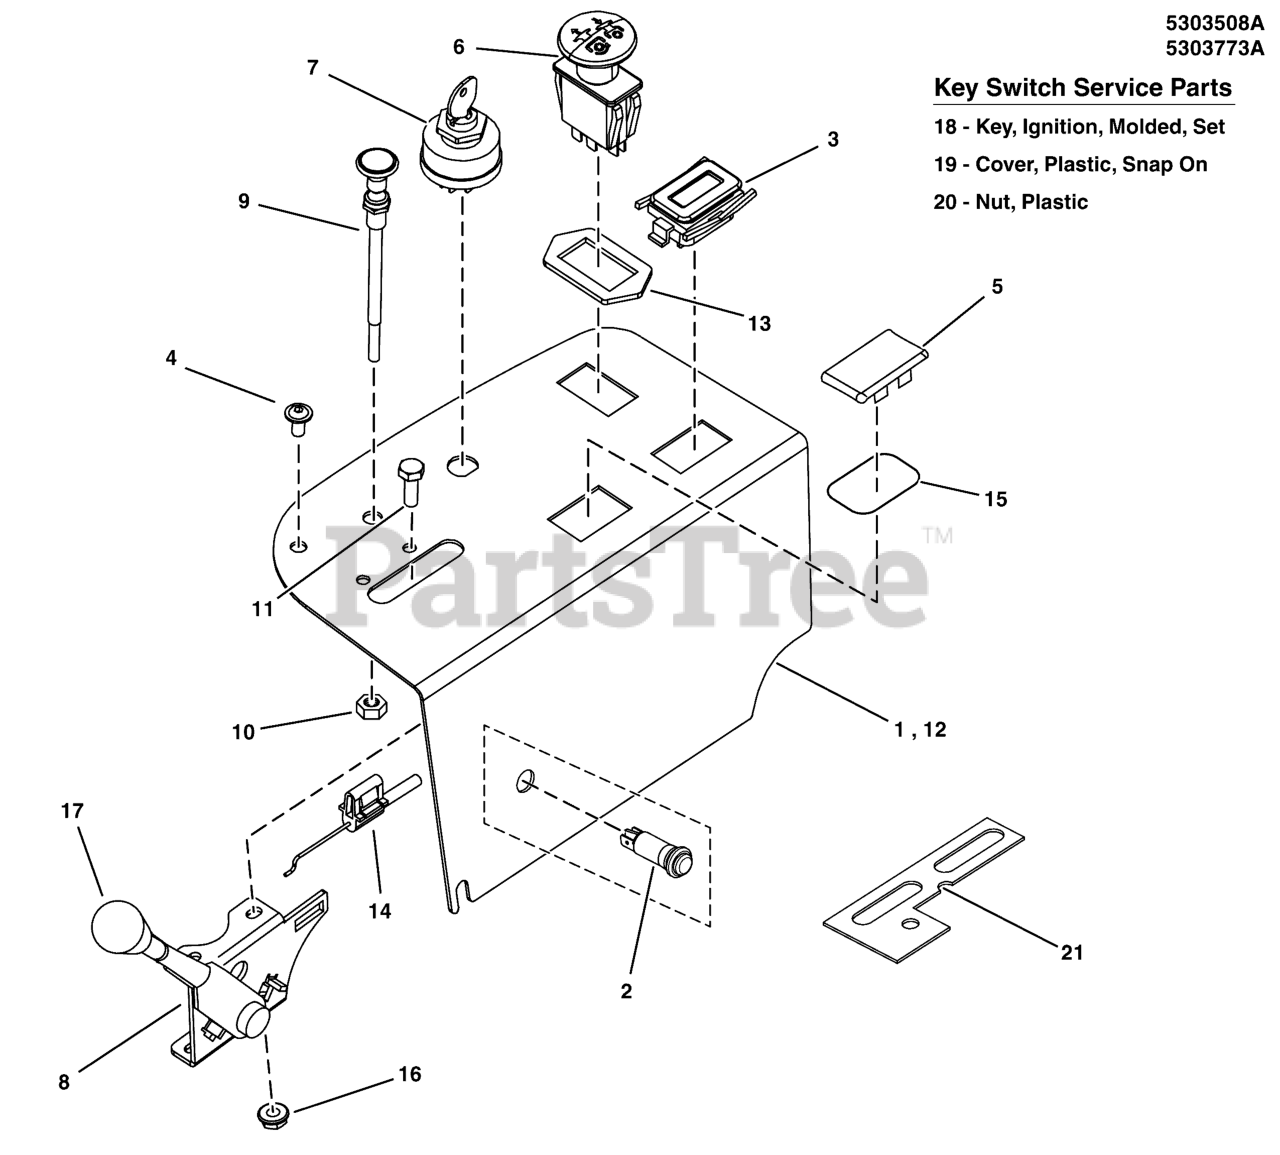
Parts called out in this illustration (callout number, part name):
1	PANEL, CONTROL, IS2100Z - BLK
2	LIGHT, INDICATOR, PANEL, LED, RED
3	* HOUR METER, ASSEMBLY
4	SCREW,ALLEN HEAD 1/4-20X.500 ZINC PHOS
5	PLUG, .820X1.44 HOLE, BLACK PLASTIC
6	SWITCH-PTO PUSH
7	SWITCH, IGNITION, 6 POST
8	LEVER, THROTTLE CONTROL, HEAVY-DUTY
9	CABLE, CHOKE CONTROL, 47
10	NUT, 3/8-24 HEX
11	SCREW, #10-24 X 3/4 ROUND PHILLIPS
12	PANEL, Control - Black
13	RING, SWITCH RETAINER
14	CABLE, THROTTLE, 42"
15	O-RING, 7/8 ID X 1/16 W
16	NUT, #10-24 HEX NYLON LOCK
17	THROTTLE CONTROL HANDLE/KNOB
18	KEY, IGNITION MOLDED SET
19	COVER, PLASTIC, SNAP ON
20	PLASTIC NUT
